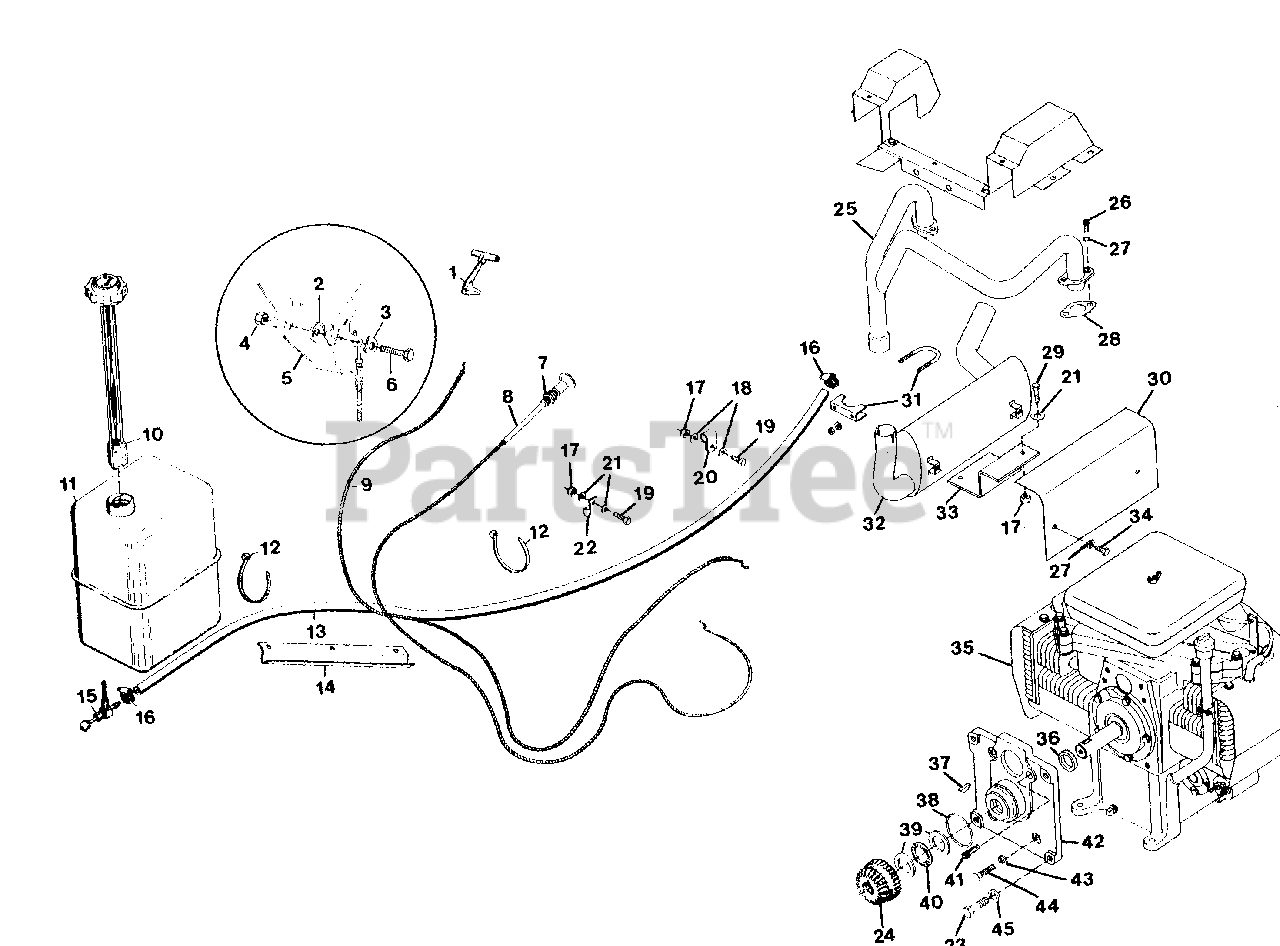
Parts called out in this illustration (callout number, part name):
1	ASSEMBLY, KNOB AND LEVER
2	WASHER, FRICTION
3	WASHER, SPRING
4	NUT, LOCK 1/4-28
5	BRACKET, MOUNTING
6	BOLT, HEX 1/4-28X.75
7	NUT, JAM 3/8-24 HEX
8	CONTROL, CHOKE
9	ASSEMBLY, CHOKE CONDUIT
10	GAUGE, GAS
11	TANK, FUEL
12	TIE, CABLE
13	LINE, FUEL
14	SHIELD, HEAT
15	VALVE, FUEL 90 DEG. REV. FLOW
16	CLAMP, HOSE
17	NUT, LOCK 5/16-18
18	WASHER, FLAT .313X.875X.065
19	BOLT, HEX 5/16-18X1.00
20	CLAMP, NYLON
21	WASHER, FLAT .343X.688X.065
22	CLAMP, NYLON
23	BOLT, HEX 1/2-13X1.75
24	GEAR, SPUR AND BEVEL, INPUT
25	HEADER, EXHAUST
26	SCREW, CAP 5/16-18X.75 SHD
27	WASHER, LOCK 5/16 REG.
28	GASKET, EXHAUST
29	BOLT, HEX 5/16-18X1.25
30	SHIELD, MUFFLER
31	CLAMP, MUFFLER U-BOLT
32	MUFFLER, EXHAUST
33	BRACKET, MUFFLER SUPPORT
34	BOLT, HEX 5/16-18X.75
35	ENGINE, 24 H.P. ONAN
36	SEAL, OIL 1.125X1.628X.250
37	KEY, WOODRUFF .25X1.125 SFT.
38	O-RING, 3.000X3.188X.094
39	RACE, BRG THRUST 1.125X1.75X.123
40	BEARING, THRUST 1.127X1.740X.078
41	SCREW, CAP 3/8-16X1.75 HSHD
42	ADAPTOR, ENGINE
43	WASHER, LOCK 3/8 REG.
44	BOLT, HEX 3/8-16X1.75
45	WASHER, LOCK 1/2 REG.
NS	SCREW, MACHINE 10-32X.50 PHD
NS	NUT, LOCK 10-32
